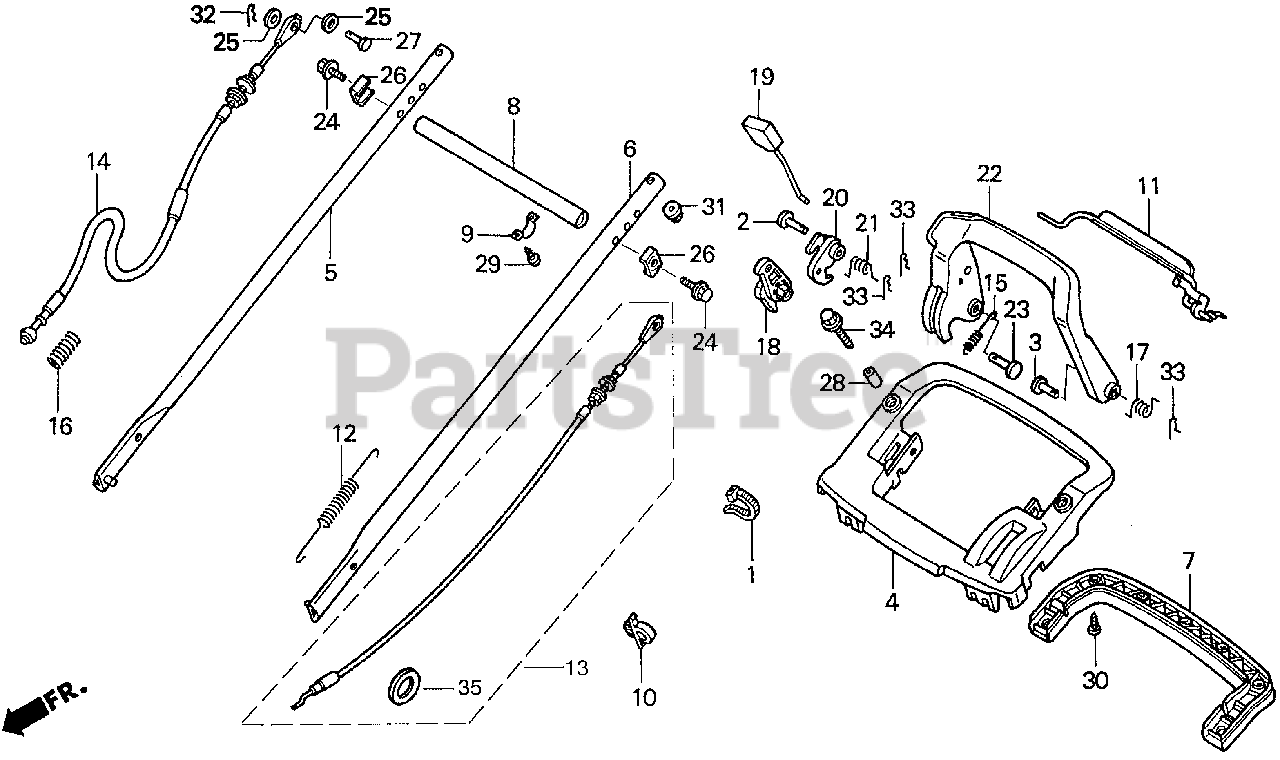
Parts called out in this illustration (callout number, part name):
1	TIE, CABLE
2	PIN, STEP BAR JOINT
3	PIN, STEP BAR JOINT
4	HANDLE (UPPER)
5	HANDLE *NH246* (LOOSY GRAY) (NOT AVAILABLE)
6	HANDLE *NH246* (LOOSY GRAY) (NOT AVAILABLE)
7	GRIP, HANDLE
8	PIPE, HANDLE CONNECTING *NH246* (LOOSY GRAY)
9	PLATE, HANDLE CONNECTING
10	CLIP, POWER STEERING SUCTION TUBE
11	LEVER, CLUTCH
12	SPRING, CLUTCH LEVER
13	CABLE, CLUTCH
14	CABLE, ROTO-STOP CLUTCH
17	SPRING, R. STOP RETURN
18	ARM, ROTO-STOP CABLE
19	ROD, RATCHET PUSH
20	LEVER, LOCK
21	SPRING, RATCHET PIN
22	LEVER, ROTO-STOP
23	PIN, SEAT BASE (8MM)
24	BOLT, HANDLE JOINT
26	WASHER, FRAME JOINT
27	PIN, CABLE JOINT (6X17)
28	COLLAR, HANDLE
29	SCREW, TAPPING (4X10) (PO)
30	SCREW, TAPPING (4X12)
31	NUT, FLANGE (8MM)
32	PIN, LOCK (6MM)
33	PIN, LOCK (8MM)
34	BOLT, FLANGE (8X45)
35	WASHER, SPECIAL (6MM)
